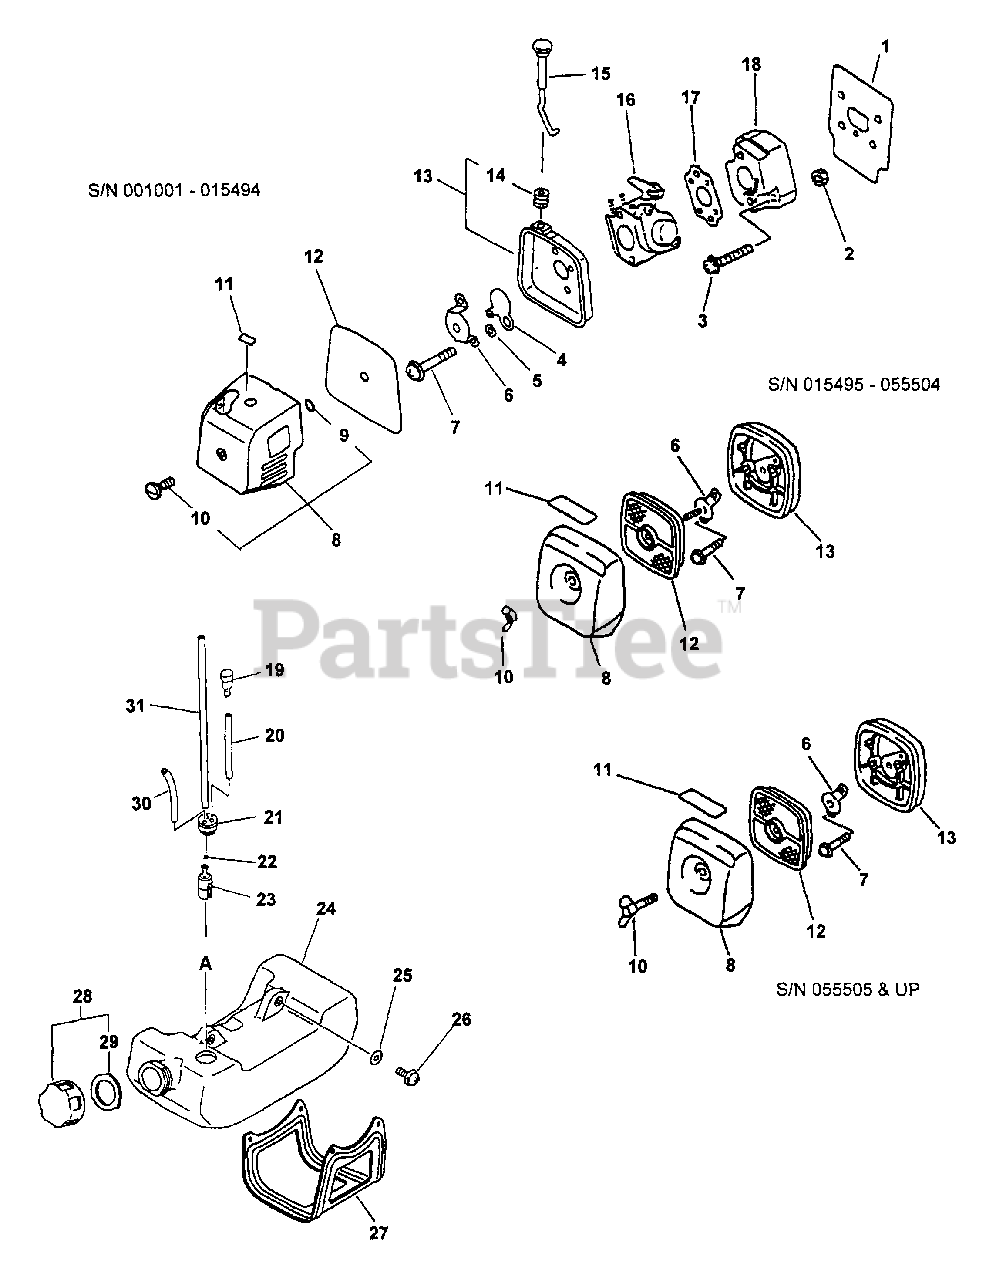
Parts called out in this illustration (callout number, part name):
1	SHIELD, INTAKE
3	SCREW - 5X20
4	SHUTTER, CHOKE
5	WASHER - 5
6	BRACKET, AIR CLEANER
6	PLATE, PREVENT
7	SCREW - 5X57
7	SCREW - 5X65
8	AIR FILTER COVER ASSY
8	COVER, AIR FILTER - BLACK
9	O-RING - 4
10	SCREW
10	WINGNUT - 6
10	THUMBSCREW
11	LABEL - CHOKE
12	FILTER, AIR
12	FILTER, AIR - SINGLE LAYER
13	CASE, AIR FILTER
13	AIR FILTER CASE ASSY
15	ROD, CHOKE
16	CARBURETOR C1U-K16
16	CARBURETOR C1U-K47
16	CARBURETOR C1U-K52
17	GASKET, INTAKE
18	INSULATOR, INTAKE
19	VENT, FUEL TANK
20	PIPE - 3X5X70 -- BLACK
21	GROMMET
22	CLIP - 6
23	FILTER, FUEL
24	TANK, FUEL
25	WASHER - 5
26	SCREW - 5X16
27	GUARD, FUEL TANK
28	CAP ASSY
29	GASKET, CAP
30	PIPE - 3X6X80 -- CLEAR
31	PIPE - 3X5X180 -- BLACK
